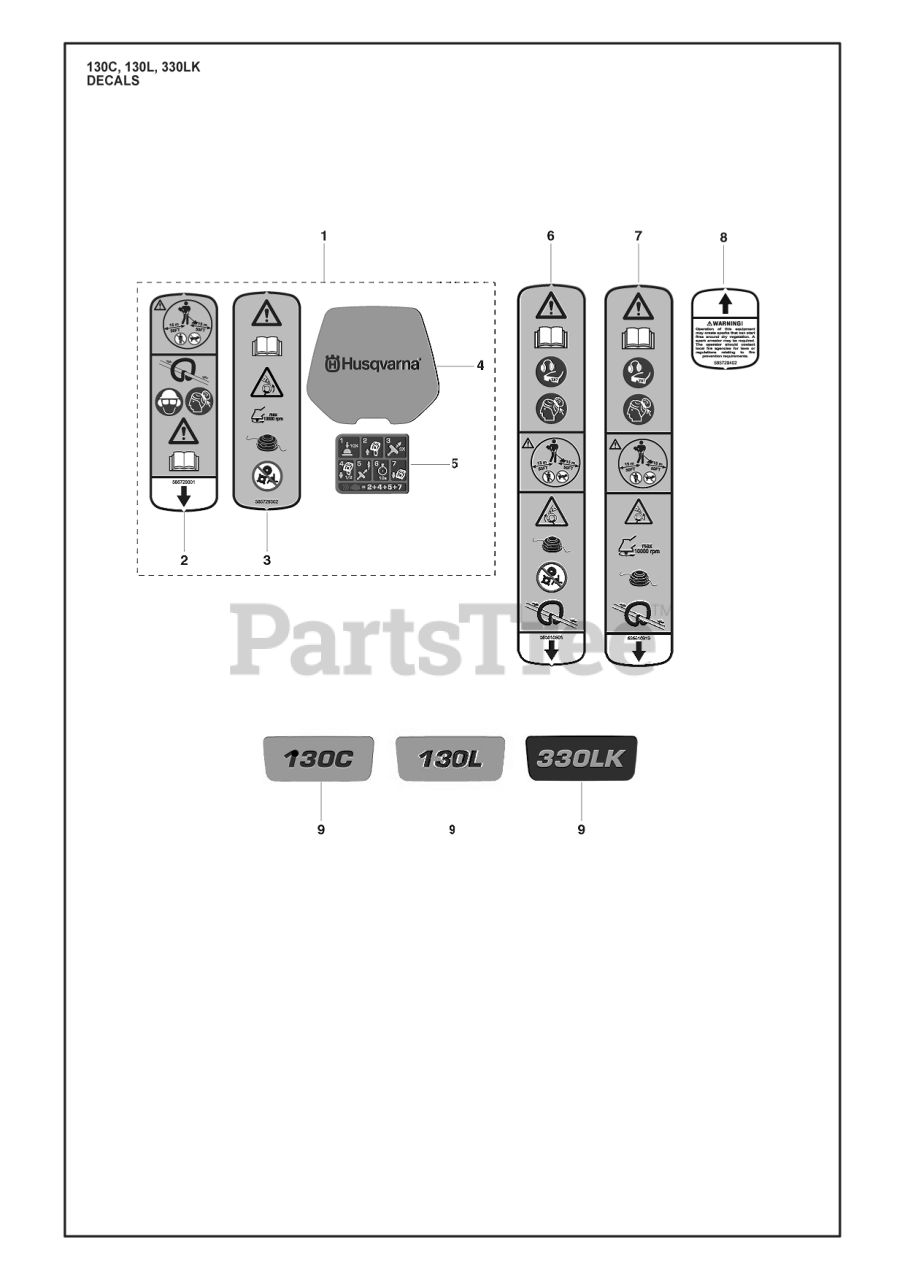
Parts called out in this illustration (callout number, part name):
4	STARTER HOUSING DECAL
5	LABEL
6	LABEL
7	LABEL
8	DECAL ARROW
9	DECAL
